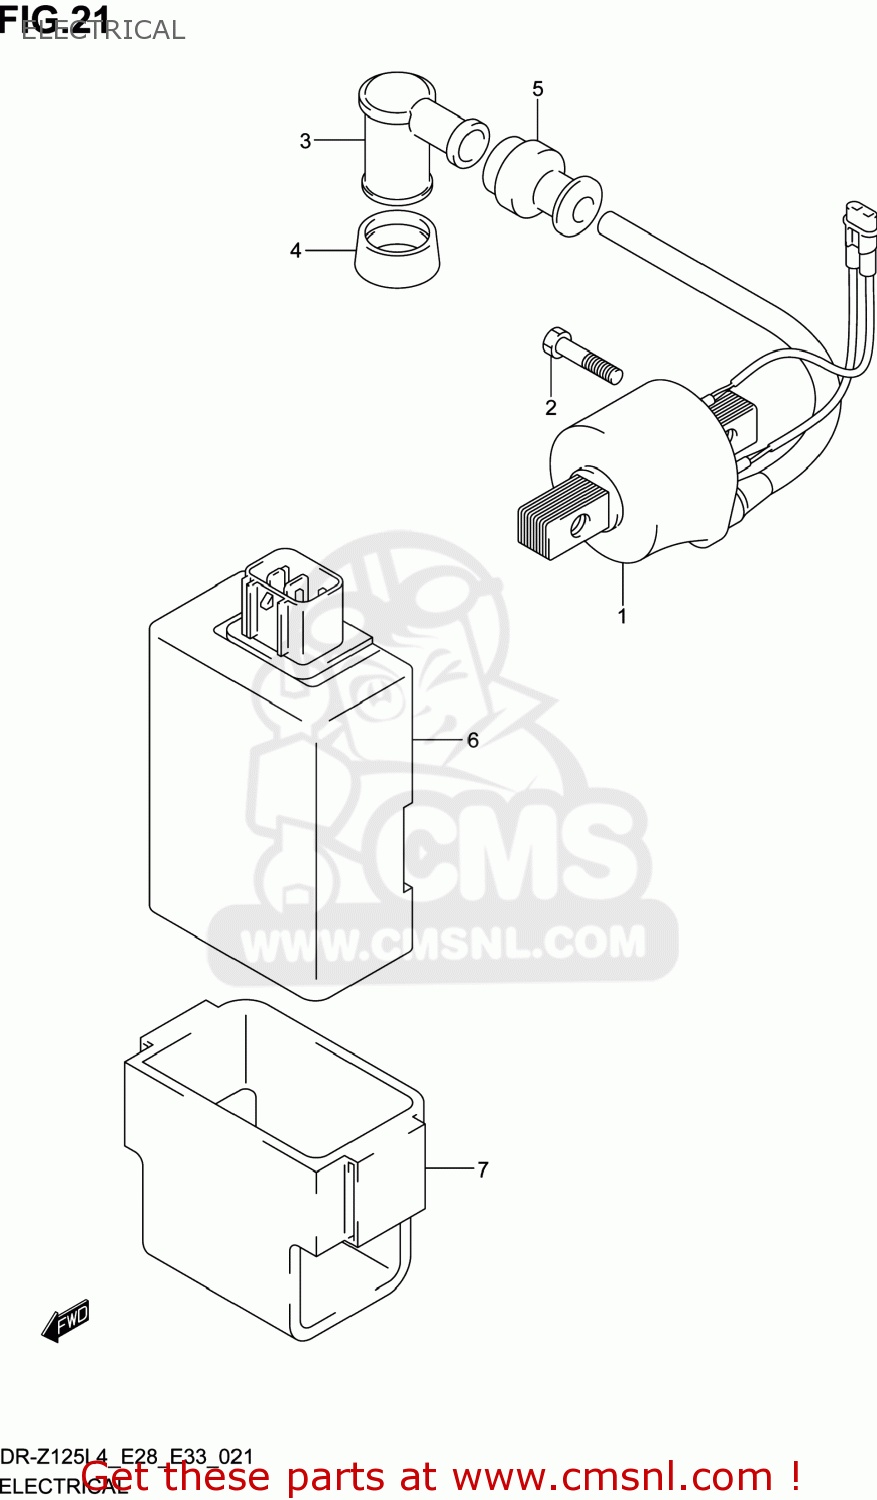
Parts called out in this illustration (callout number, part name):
1	COIL ASSY,IGNITION
2	BOLT
3	CAP ASSY,SPARK PLUG
4	SEAL,SPARK PLUG
5	SEAL,HIGH TENSION CORD
6	CDI UNIT
7	CUSHION,CDI UNIT
